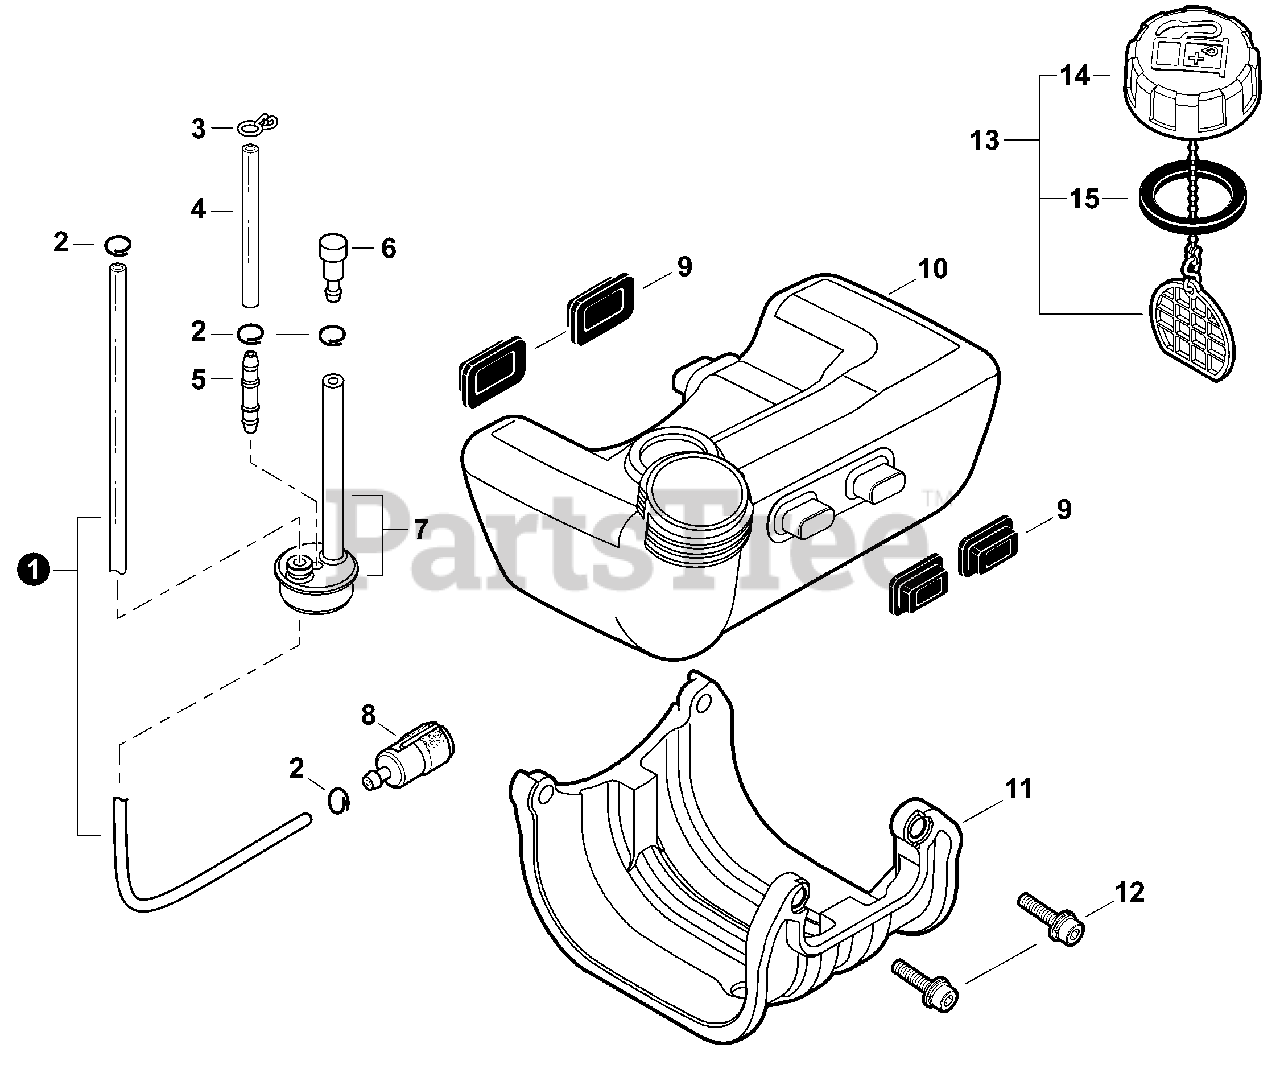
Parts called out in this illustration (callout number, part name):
1	PIPE, FUEL 3.3×6×160
2	CLIP Ø6
3	CLIP, SPRING Ø5.2
4	PIPE, FUEL RETURN
5	CONNECTOR, PIPE
6	VENT ASSY
7	GROMMET, FUEL W/VENT PIPE
8	FILTER, FUEL 125-528
9	CUSHION, FUEL TANK
10	TANK, FUEL
11	GUARD, PLASTIC FUEL TANK
12	BOLT M5×20
13	CAP ASSY, FUEL
14	CAP, FUEL
15	GASKET, FUEL CAP
